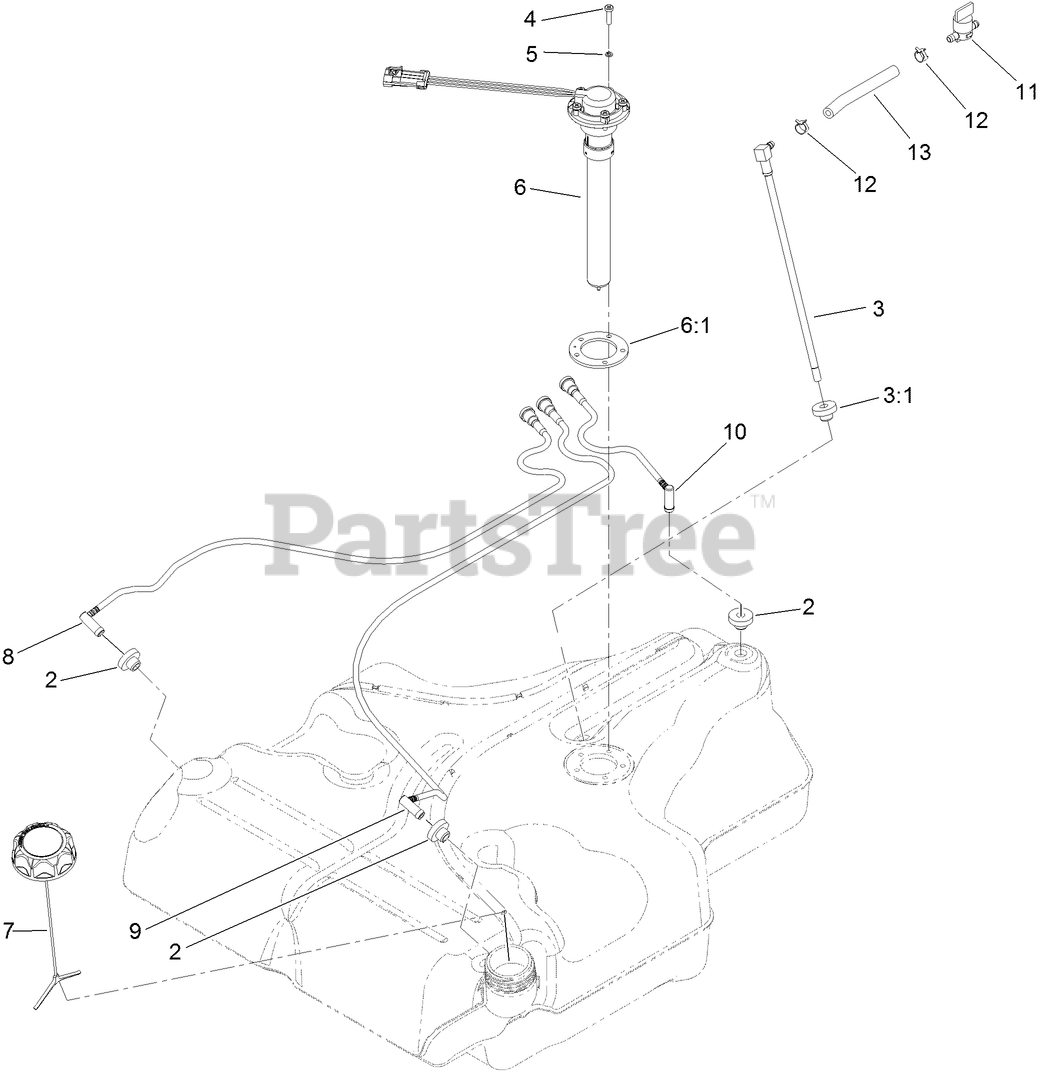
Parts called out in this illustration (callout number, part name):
2	BUSHING
3	FUEL LINE KIT (WITH GROMMET)
3:1	BUSHING
4	SCREW-PAN
5	WASHER-LOCK
6	SENDER-LEVEL, FUEL
6:1	GASKET-SENDER, FUEL
7	CAP-FUEL, RATCHETING
8	RH VENT LINE KIT (WITH GROMMET)
9	LH VENT LINE KIT (WITH GROMMET)
10	REAR VENT LINE KIT (WITH GROMMET)
11	VALVE-FUEL
12	CLAMP-HOSE
13	HOSE-FUEL
